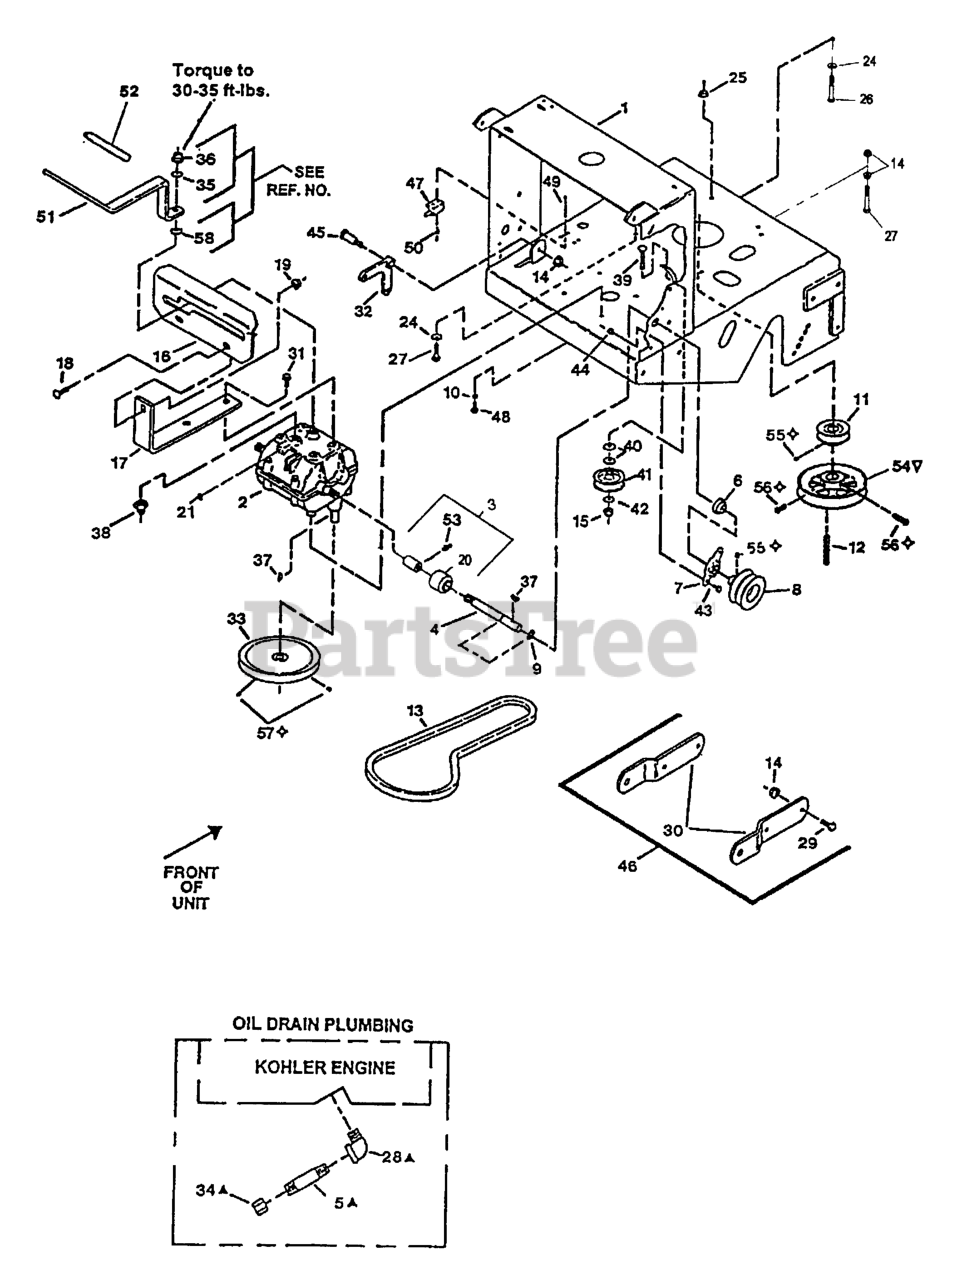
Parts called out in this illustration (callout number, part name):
1	Rear Deck
3	ASM,COUPLER/ZERK
4	SHAFT-TRANSMISSION
5	NIPPLE
6	BEARING-SHAFT
7	FLANGE-OUTPUT
9	RING-RETAINING
10	WASHER-LOCK
11	SHEAVE-TRANSMISSION
12	KEY,MACH 1/4X1/4X2-5/8
13	BELT,TRANS DRIVE
14	NUT-HHF, WHIZ
15	NUT-LOCK, NI
17	BRACKET-PLATE, SHIFT
18	BOLT-CARR
20	GUARD-COUPLER
21	BALL,DETENT (SERVICE ONL
23	KIT,TRANSMISSION UPDATE
24	WASHER-SPRING
25	NUT-HF
26	SCREW-HH
27	SCREW-HH
28	FITTING-ELBOW-90
29	SCREW-HH
31	SCREW-HWH, THREAD CUT
32	BELLCRANK
33	SHEAVE-TRANSMISSION
34	CAP-HEX
35	WASHER-BELLEVILLE
36	NUT-LOCK
37	KEY-WOODRUFF
38	SWITCH-START, NEUTRAL
39	SCREW-HH
40	WASHER-FLAT
42	WASHER-FLAT
43	SCREW-HH
44	NUT-LOCK, NI
45	BOLT-SHOULDER
46	Sulky Hitch Kit, Metro
47	SWITCH-OPEN, NORMALLY
48	SCREW-HH
49	SCREW-PPH
50	NUT-LOCK, NI
51	Shift Lever
53	FITTING-GREASE
54	SHEAVE-SPLIT
55	SCREW-SET
56	SCREW-SET
57	SCREW-HSH
60	SCREW-HH
61	SPACER-CLUTCH
62	WASHER-SPRING
63	SHEAVE-TRANSMISSION
65	KEY-SQUARE
